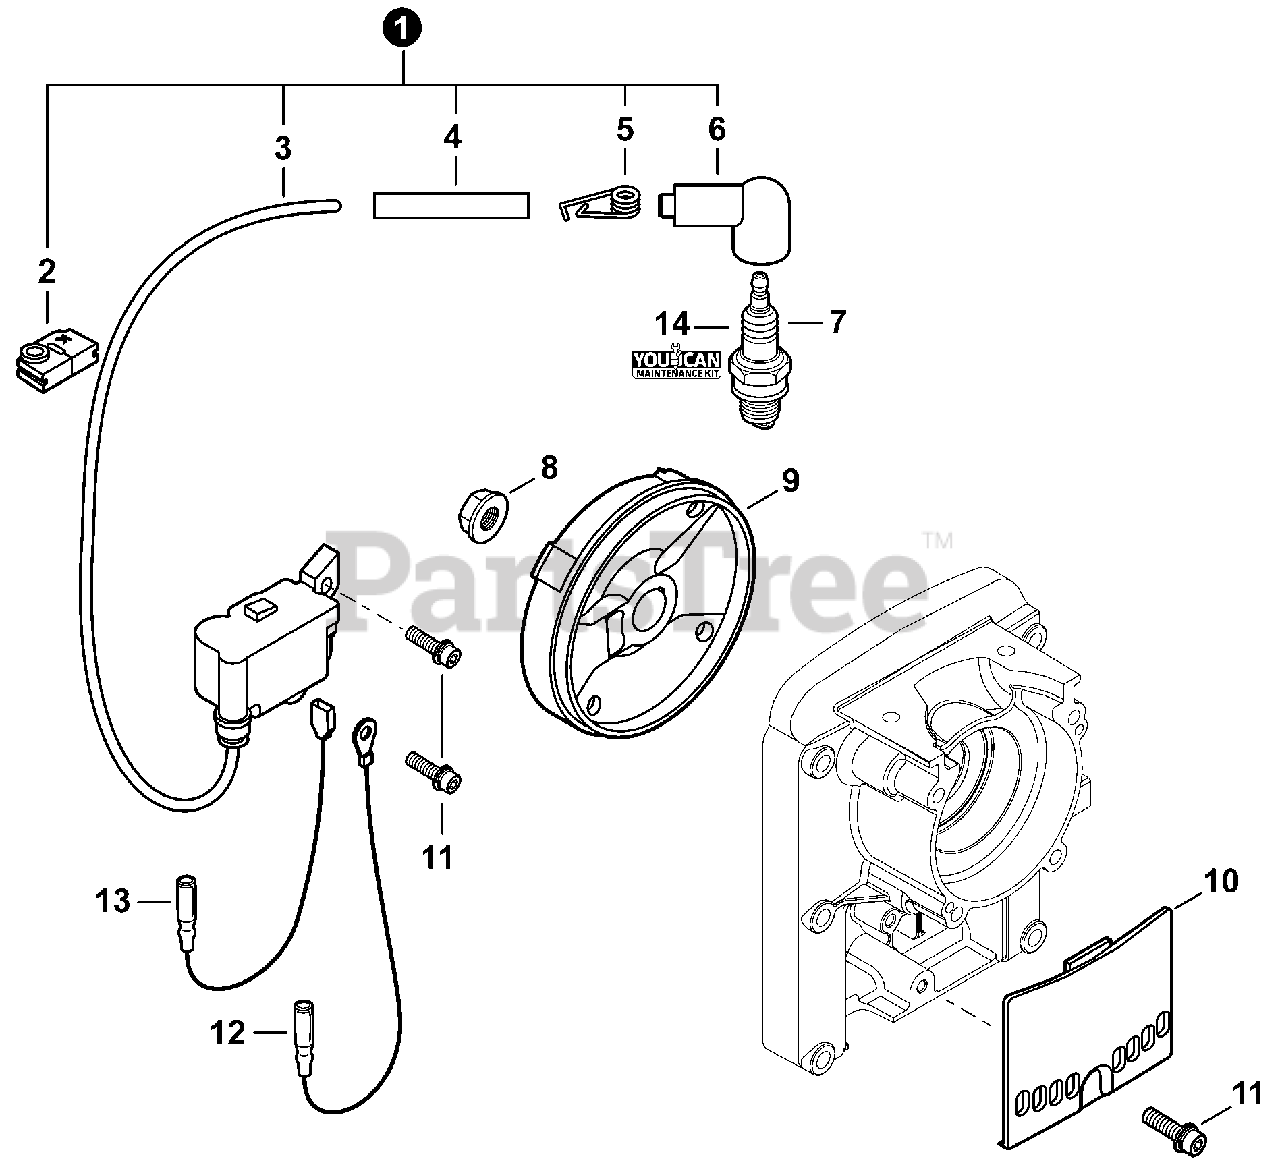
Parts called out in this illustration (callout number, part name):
1	COIL ASSY, IGNITION
2	GROMMET
3	COIL, IGNITION
4	TUBE, INSULATOR
5	TERMINAL, SPARK PLUG
6	CAP, SPARK PLUG
7	SPARK PLUG - BPMR8Y
9	FLYWHEEL
10	COVER, DUST
11	BOLT M4×20
12	LEAD - GROUND
13	LEAD - IGNITION L= 170
14	TUNE-UP KIT - YOUCAN™
